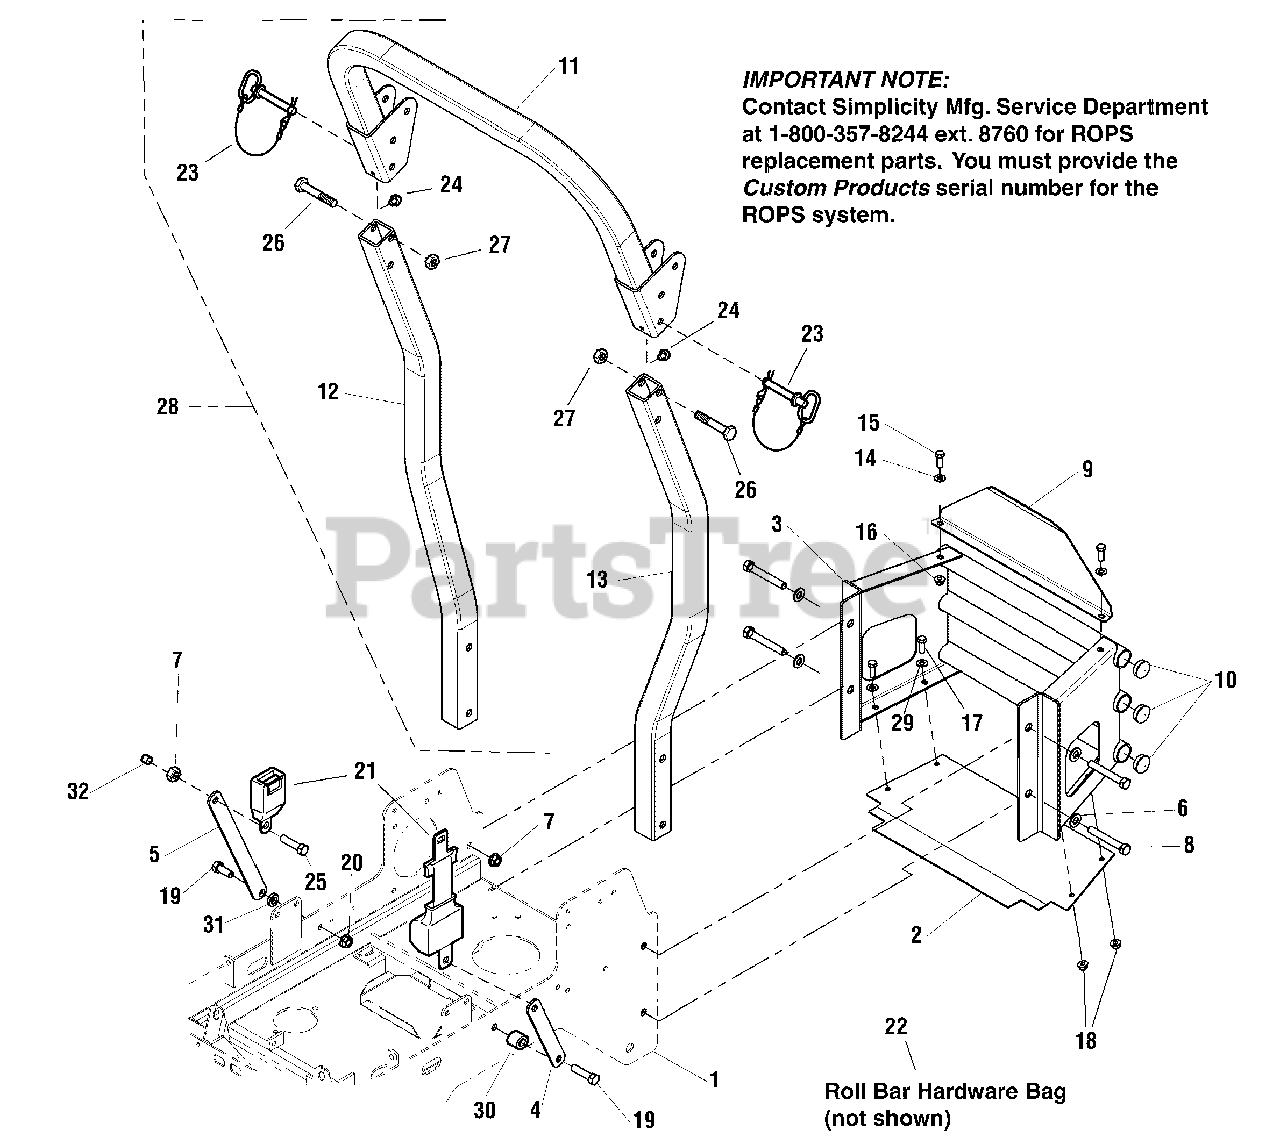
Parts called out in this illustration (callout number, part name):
1	MAIN FRAME
2	HEAT SHIELD
3	BUMPER
4	PLATE, SEAT BELT ANCHOR - BLK
5	MOUNT, SEAT BELT - RH - BLK
6	WASHER, 1/2 SAE
7	NUT, 1/2-13 HEX NYLOCK FLANGE
8	BOLT, 1/2-13 X 3-1/4" GD5
9	CARB PROTECTOR PLATE
10	PLUG, PANEL, 1.25 BLACK
11	ROLL BAR TOP LOOP
12	ROLL BAR POST, RH
13	ROLL BAR POST, LH
14	WASHER, 3/8 SAE
15	BOLT, 3/8-16 X 1" GD5
16	NUT, 3/8-16 X 1" GD5
17	BOLT, 5/16-18 X 3/4 GD5
18	NUT, 5/16-18 HEX NYLOCK FLANGE
19	BOLT, 1/2-13 X 1-3/4 GD5 YZ
20	NUT, 1/2-13 HEX NYLOCK FLANGE
21	SEAT BELT ASSEMBLY, STANDARD
21	SEAT BELT ASSEMBLY, EXTRA LONG
22	ROLL BAR HARDWARE BAG
23	PIN, HITCH, BLACK W/ PLASTIC LANYARD
24	RUBBER BUMPER
25	SCREW, 1/2-13 X 1.00, SHCS
26	*BOLT
27	*NUT
28	ROPS (Call 1-800-933-6175 x708 if replacing a ROPS)
29	WASHER, 5/16" SAE
30	SPACER, .52 X 1.00 X .75
31	SPACER, .515 X 1.00 X .218
32	CAP, VINYL
